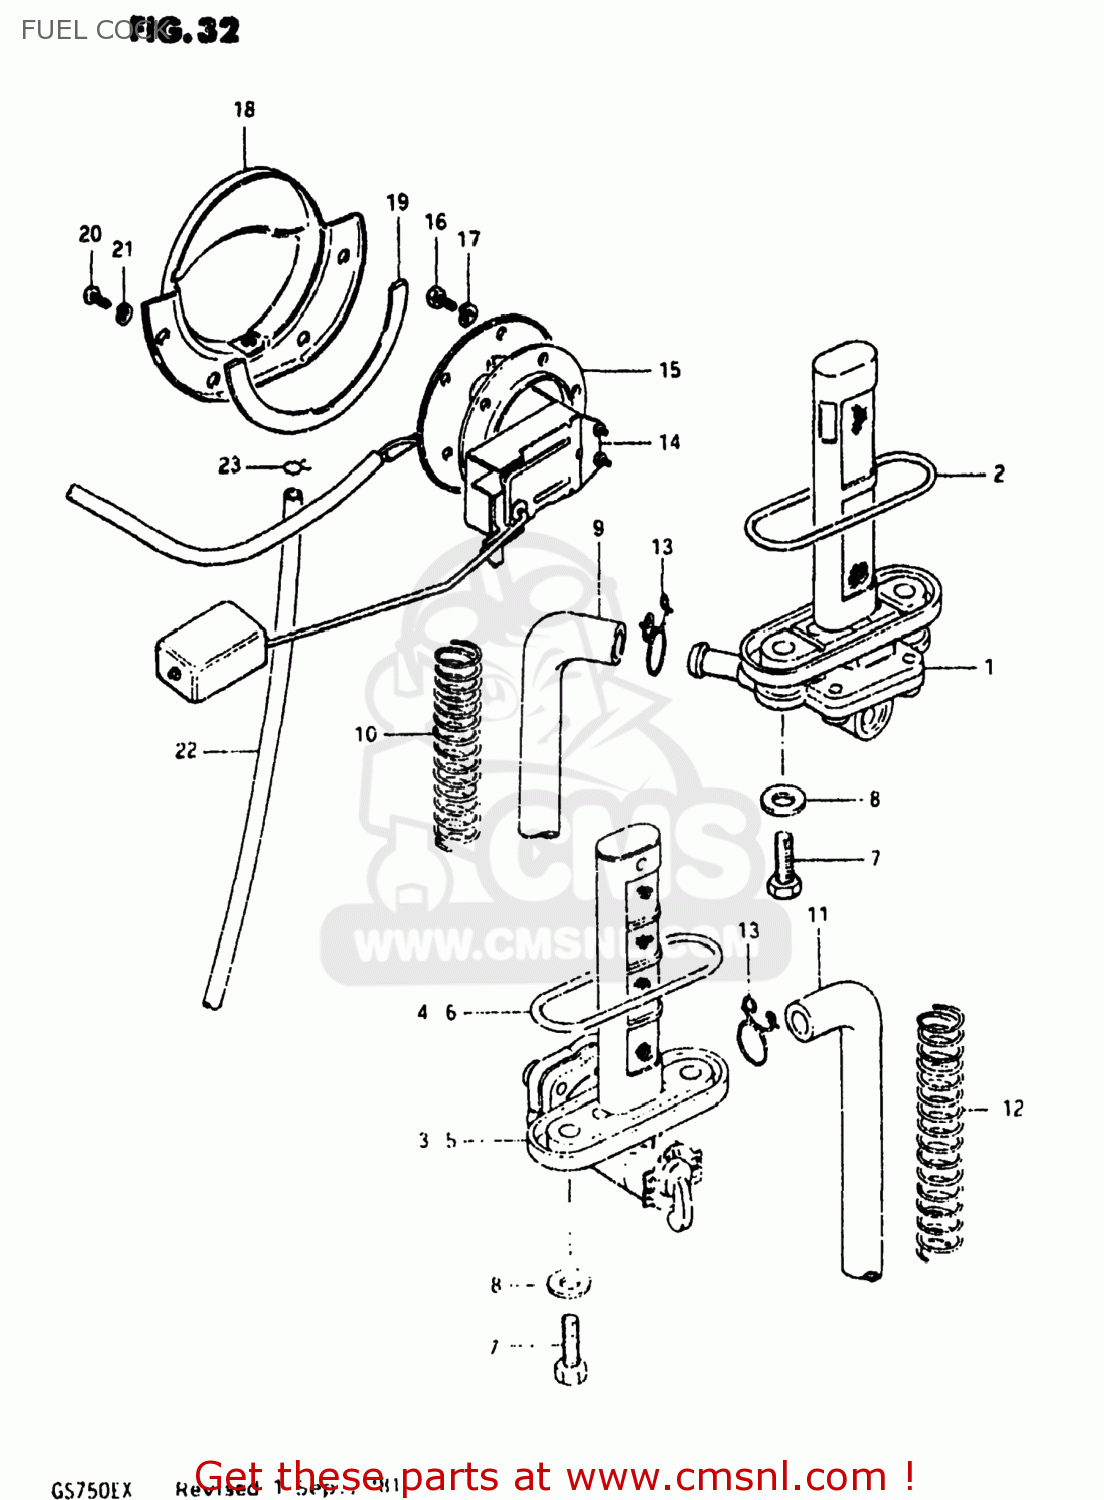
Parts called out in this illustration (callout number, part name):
1	COCK ASSY,FUEL
2	GASKET (NAS)
3	COCK ASSEMBLY,FUEL
4	O RING
5	COCK ASSEMBLY,FUEL
6	O RING
7	SCREW (6X25)
8	GASKET
9	HOSE
10	SPRING
11	HOSE
12	SPRING
13	CLIP
14	GAUGE ASSEMBLY,FUEL LEVEL
15	GASKET,FUEL LEVEL GAUGE (NAS)
16	BOLT
17	LOCK WASHER
18	PLATE,FUEL DRAIN
19	GASKET,FUEL DRAIN PLATE (NAS)
20	SCREW
21	LOCK WASHER
22	HOSE,FUEL
23	CLIP
